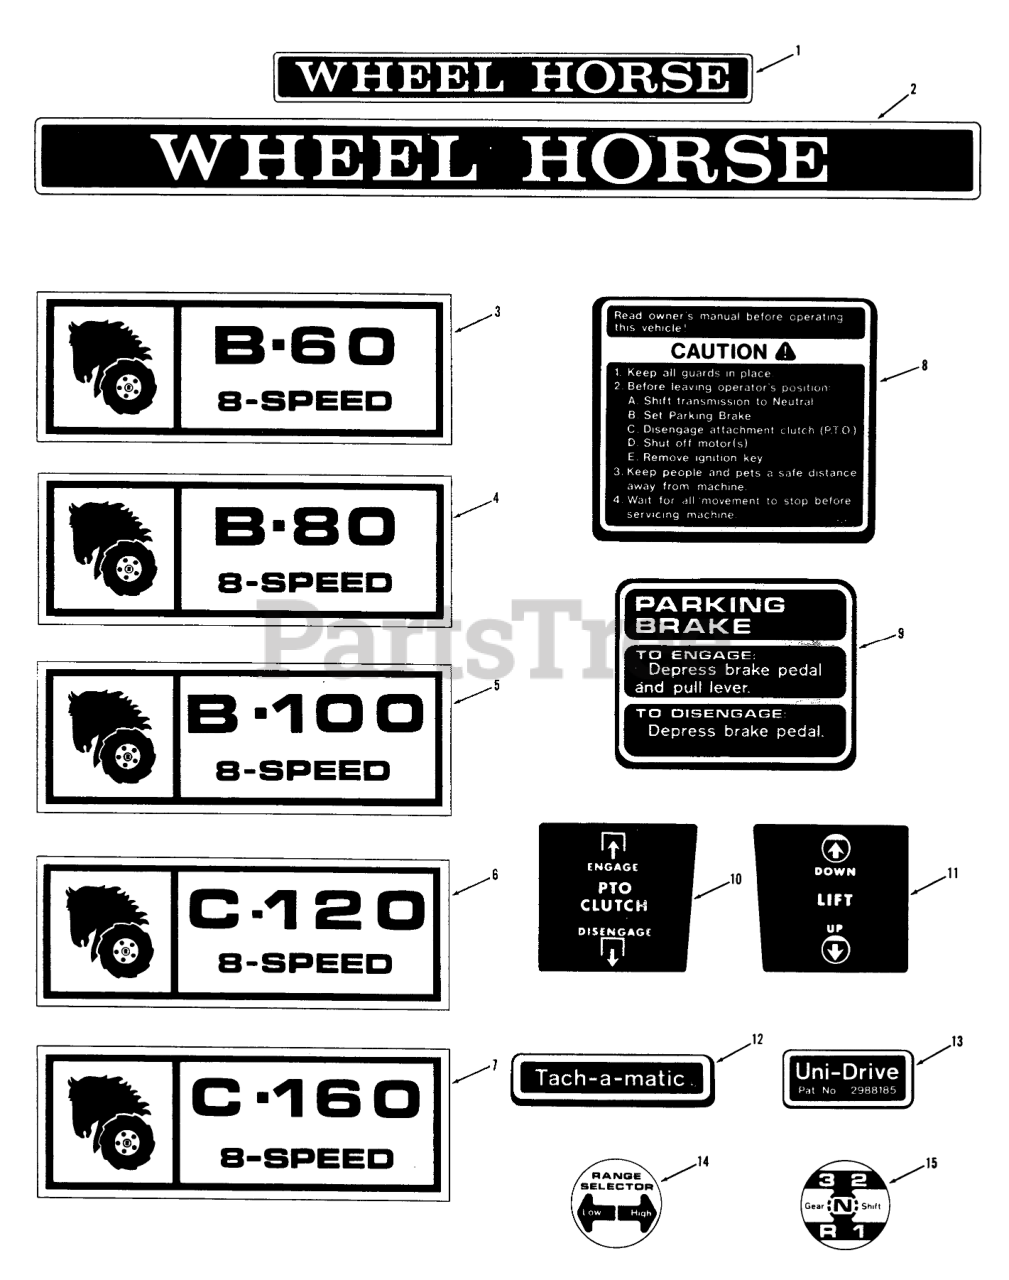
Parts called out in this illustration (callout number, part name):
1	DECAL-WHEEL HORSE
2	Decal
3	Decal-B-60
4	Decal-B-80
5	Decal-B-100
6	DECAL C-120 8-SPEED
7	Decal-C-160
8	Decal-Caution
9	Decal-Park Brake
10	Decal
11	DECAL-HAND LIFT
12	Decal-Tach-a-matic
13	Decal-Unidrive
14	DecaI-Hi-Lo
15	DECAL-4 SPD SHIFT
